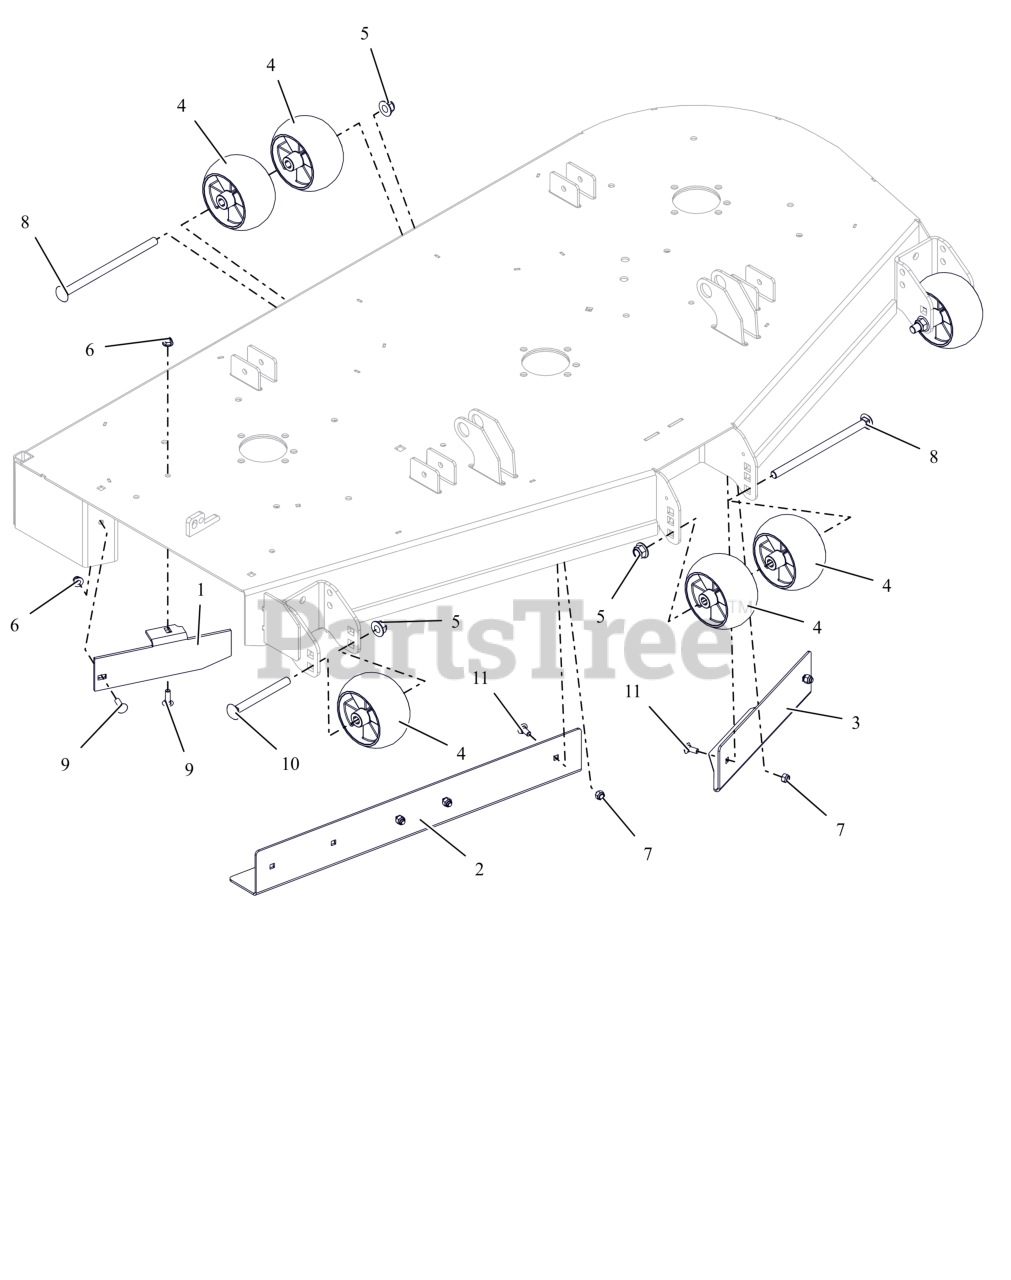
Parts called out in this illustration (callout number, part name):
1	60" DISCHARGE BAFFLE - RED
2	BAFFLE, 60" RH VACUUM (RED)
3	BAFFLE, 60" LH VACUUM (RED)
4	WHEEL, ANTI SCALP - 5X3 CTR W/RIBS
5	NUT,NYL-FLG .50-13 GF ZCC
6	NUT,NYL-FLG .31-18 GF ZCC
7	NUT,NYL .31-18 G5 ZCC
8	BTL,RHSN .500-13 X 8.5S G5 ZCC
9	BLT,RHSN .31-18X1.00 G5 ZCC
10	BLT, RHSN .50-13X5.00 G5 ZCC
11	BLT,RHSN .31-18X.75 G5 ZCC
